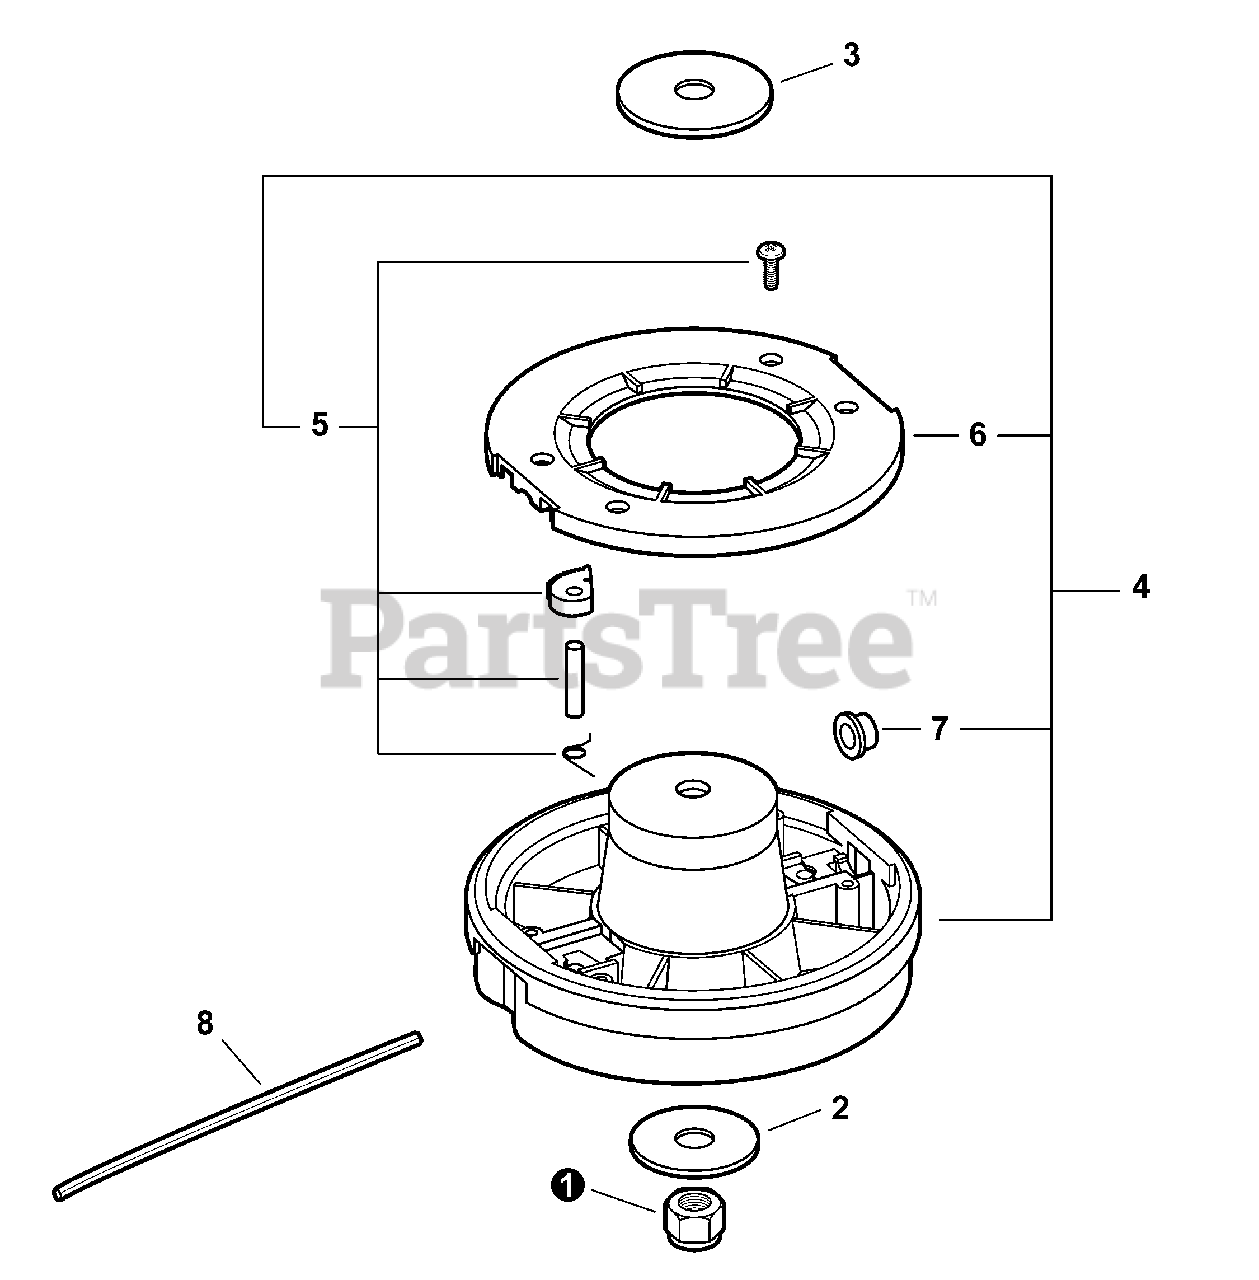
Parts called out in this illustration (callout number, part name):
1	NUT, LOCK
2	WASHER 10
4	TRIMMER HEAD, RAPID-LOADERT- 2 LINE
5	PAWL KIT
6	COVER, TOP
7	EYELET (PACKAGE OF 3)
8	LINE, TRIMMER - 0.080 DIA. (PKG. OF 20)
